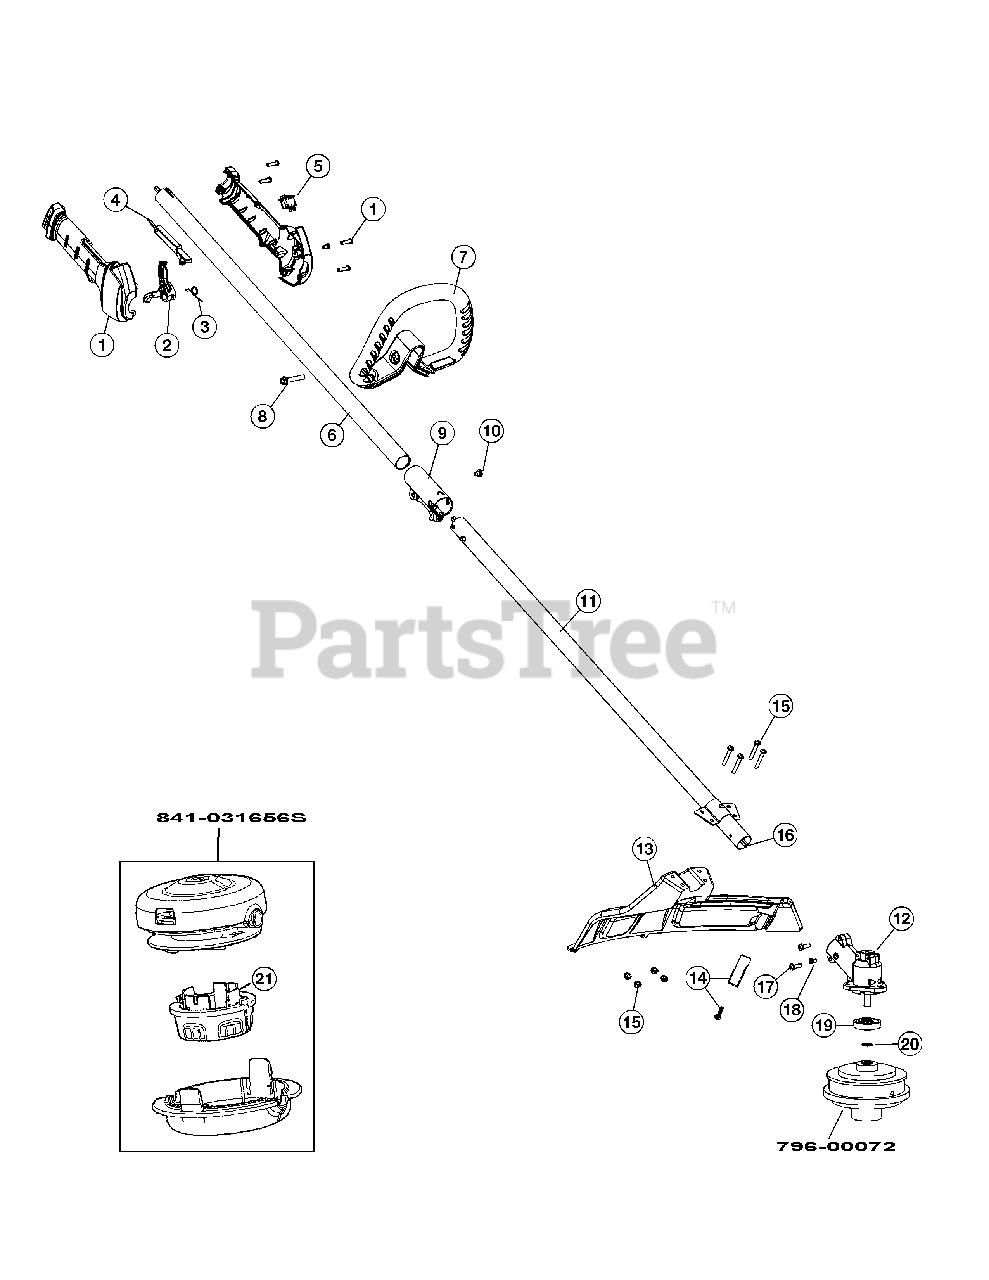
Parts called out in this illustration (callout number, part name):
1	Throttle Housing Assembly
2	Throttle Trigger
4	Throttle Lock-out
6	Upper Drive Shaft Housing Assembly
7	D-Handle Assembly
9	Split Boom Coupler
10	Coupler Anti-Rotation Screw
11	Lower Drive Shaft Housing Assembly
13	Shield Assembly
14	Blade Assembly
15	Shield Mounting Screw & Nut
16	Lower Flexible Drive Shaft
17	Gearbox Mounting Hardware
18	Anti-Rotation Screw
19	Blade Driver
796-00072	Cutting Head Assembly
841-031656S	Cutting Head Assembly
